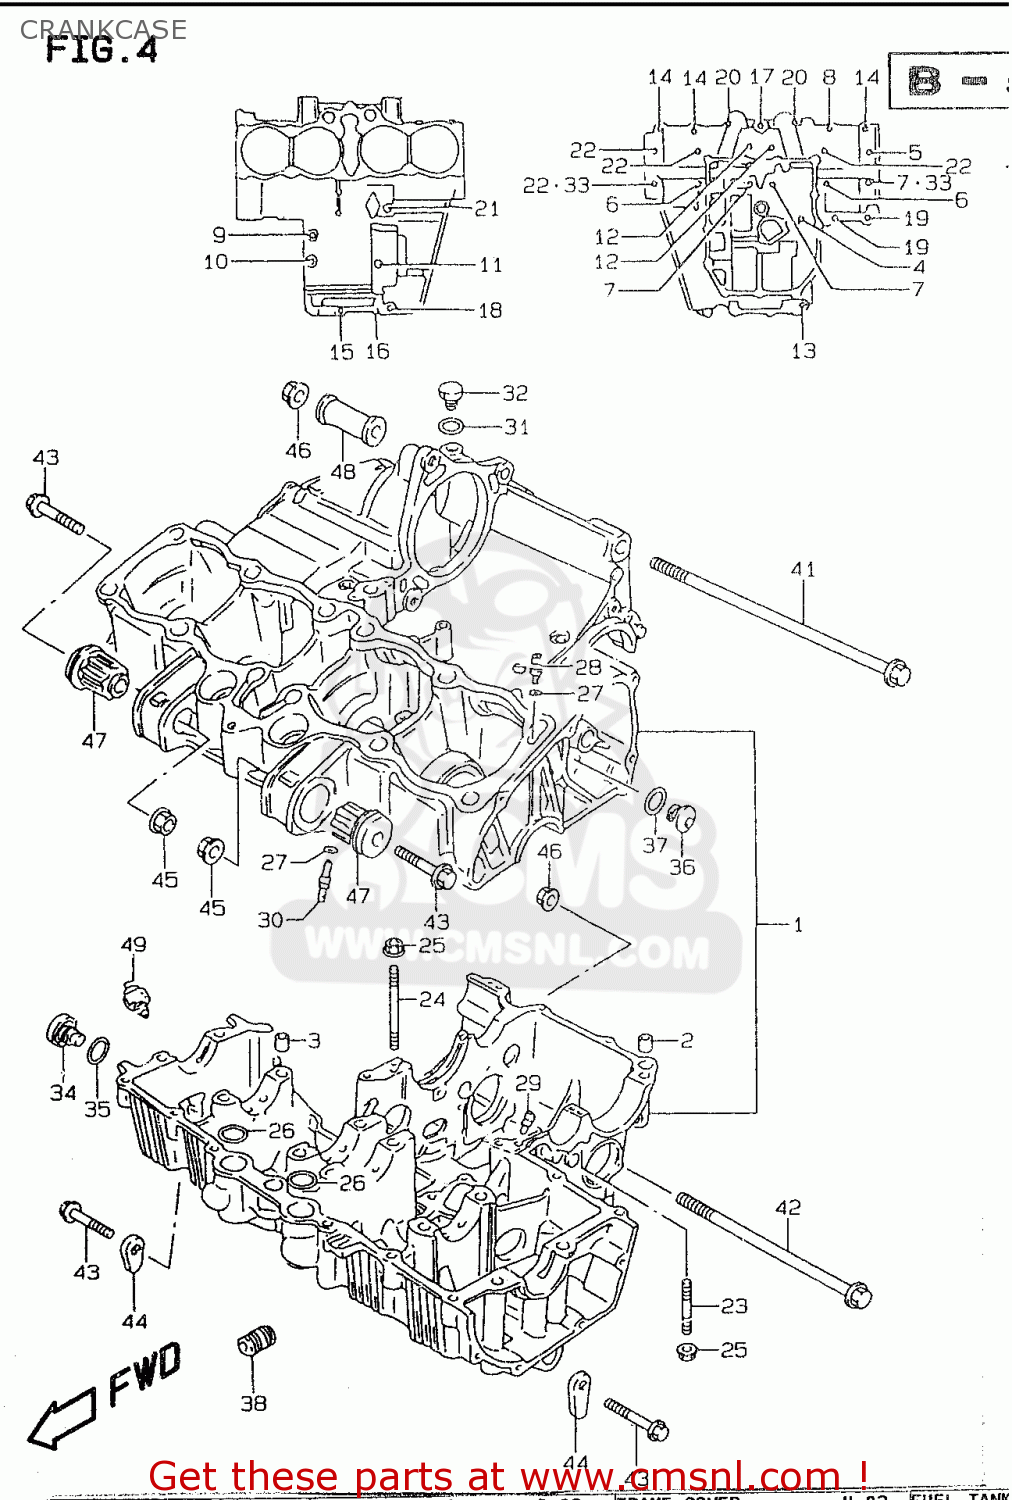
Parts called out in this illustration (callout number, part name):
1	CRANKCASE SET
2	PIN(10.4X13X22)
3	PIN(8.4X11X20)
4	BOLT(6X105)
5	BOLT(8X105)
6	BOLT(8X125)
7	BOLT(8X115)
8	BOLT
9	BOLT
10	BOLT,CL.COVER
11	BOLT
12	BOLT
13	BOLT
14	BOLT
15	BOLT
16	BOLT
17	BOLT
18	BOLT
19	BOLT, HYDRAULIC UNIT NO.2
20	BOLT
21	BOLT
22	BOLT(8X95)
23	STUD BOLT
24	STUD BOLT
25	NUT
26	O RING(D:2.5,ID:21)
27	O RING(D:1.2,ID:4)
28	JET,AIR
29	JET
30	JET,OIL GALLERY
31	GASKET(12.1X16.2X3.7) (NAS)
32	PLUG(12X9)
33	GASKET(8.5X17X2.3) (NAS)
34	PLUG
35	O RING(D:2.4,ID:16.8)
36	PLUG
37	GASKET(13.8X18.8X4.8) (NAS)
38	UNION,OIL STAND
39	PLATE,CRANK THRUST
40	PLATE,CRANK THRUST
41	BOLT(10X180)
42	BOLT(10X130)
43	BOLT
44	NUT
45	NUT
46	NUT
47	BUSH,ENGINE MOUNTING
48	SPACER,ENGINE MOUNT(L27)
49	SWITCH ASSEMBLY,OIL PRESSURE
